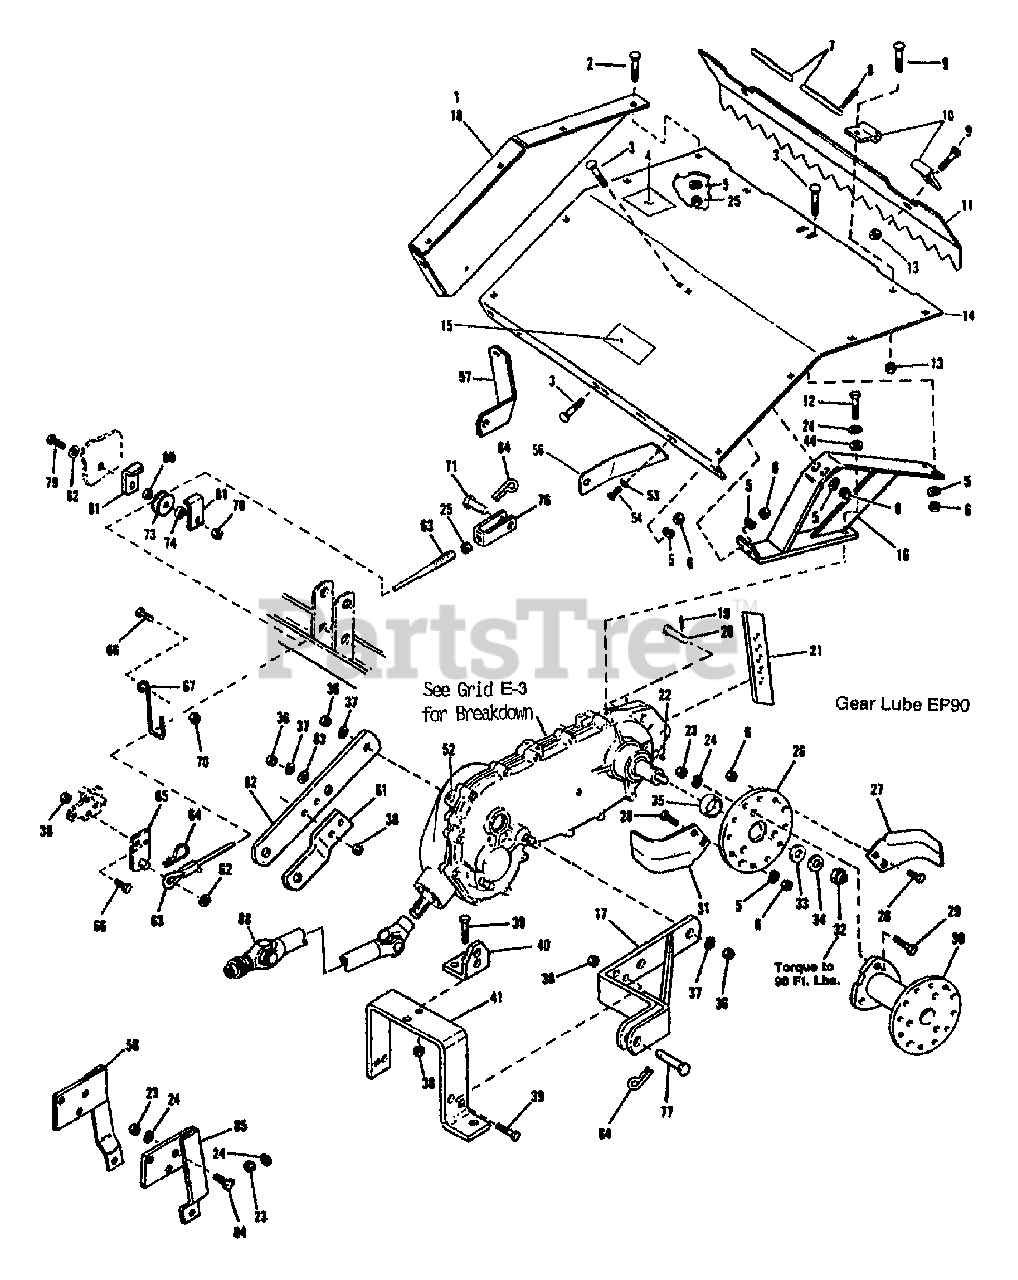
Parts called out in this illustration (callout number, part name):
2	SCR-CARR 3/8-16X.75 G5 ZP
3	SCR-CARR 3/8-16X1.00
4	DECAL-LOGO
5	WASHER-LK .375 @ DEPL
6	NUT-LOCK 3/8-16
8	PIN-COTTER .09X.75 ZP
9	SCR-CARR 5/16-18X.75
11	BOARD-LEVELING
12	SCR-HH 1/2-13X1.25 G5 ZP
13	NUT-HFLK 5/16-18 ZP
15	DECAL-OPEI CAUTION
16	SUPPORT
17	ASSM-LIFT ARM
18	HOOD-LH SIDE
19	PIN-COTTER .120X1.00 ZP
20	PIN-CLEVIS .5X2.5 ZP
22	PIN-CLIP .08
23	NUT-HEX JAM 1/2-13
24	WASHER-LK .5
25	NUT-HEX/JAM 3/8-16
28	SCR-HH 3/8-16X1.25
29	SCR-HH 1/2-13X1.75 G5 ZP
30	SPACER-TINE
31	TINE
33	WASHER-SPACER
34	WASHER-1.41X.656X.18 SPECIAL
35	SLEEVE
36	NUT-HEX
37	WASHER-LK 1.072X.634X.156
38	NUT-HFLK 3/8-16 ZP
39	SCR-HFLK 3/8-16X1.75 G5ZP
40	BRKT-CABLE ANCHOR
44	WASHER-1.06X.531X.1 ZP
52	PLUG-PIPE
53	WASHER-LK .375
54	SCR-HH 3/8-16X1.0 G5 ZP
56	BRKT-SUPT LH
58	ASSM-ARM HITCH RH
61	PLATE-DOUBLER
62	WASHER-1.06X.531X.1 ZP
63	CABLE-LIFT
64	PIN-HITCH .125X2.56 ZP
66	SCR-HFLK 3/8-16X1.00 ZP
67	GUIDE-CABLE
70	NUT-H/LK 3/8-16
71	PIN-CLEVIS .5X1.25
74	SPACER-.75X.53X.656
76	YOKE-CABLE
77	PIN-CLEVIS
79	SCR-HH 1/2-13X2.5 G5 ZP
84	SCR-HH 1/2-13X1.25 G5 ZP
85	ASSM-ARM HITCH LH
88	SHAFT-DRIVE
